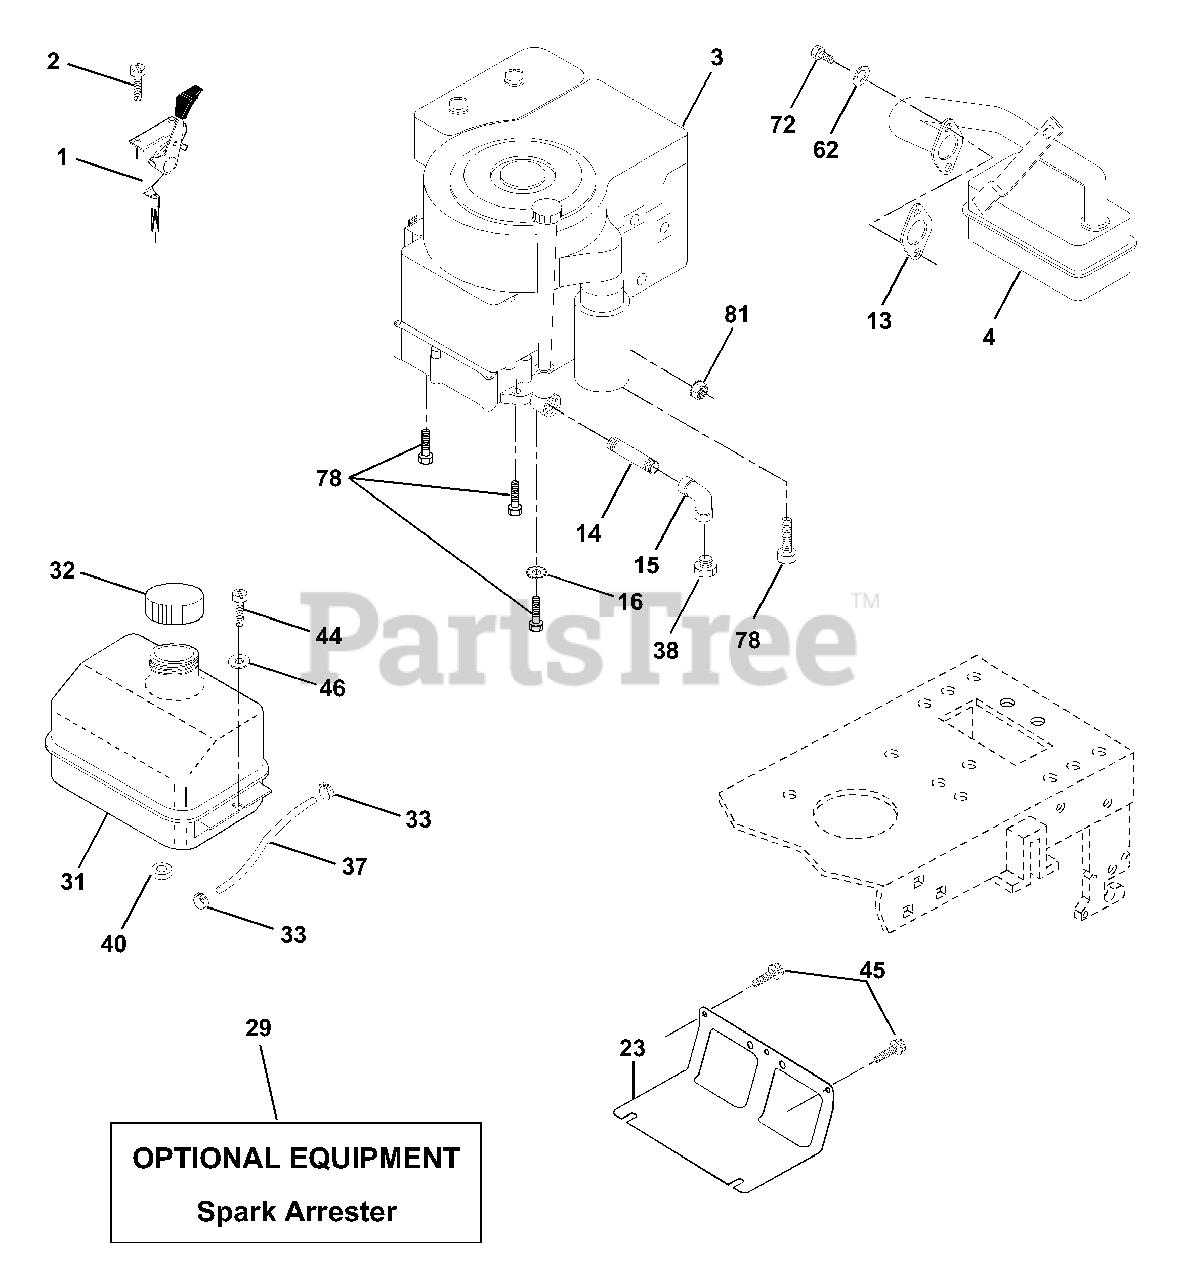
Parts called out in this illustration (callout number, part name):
1	Control Th/ch Flag
2	Screw Hex Thd Cut 1/4-20x5/8 T
4	Muffler Exhaust B&S Lc
13	Gasket Eng 1 313 Id Tin Plated
14	Nipple Pipe 3/8 Npt X 3"
15	Elbow Std 90 Degree 3/8-18 Npt
16	Washer Lock Ext Tooth 3/8
23	Shield BRN/DBR Guard
29	Kit Spark Arrestor (Flat Scrn)
31	Tank Fuel Front
32	Cap Asm Fuel
33	Clamp Hose
37	Line Fuel 20"
38	Oil Drain Plug
40	Bushing Snap Nyl Blk Fuel Line
44	Screw Thdrol 1/4-20 x 3/4
45	Screw Hex Wsh Thdrol 3/8-16
46	Washer 9/32 X 7/8 X 16 Ga
62	Washer Lock Hvy Hlcl Spr
72	Screw Hexcap 5/16-18 x 5/8
78	Screw 3/8-16 x 1-1/4
81	Nut Keps Hex 1/4-20 Unc
